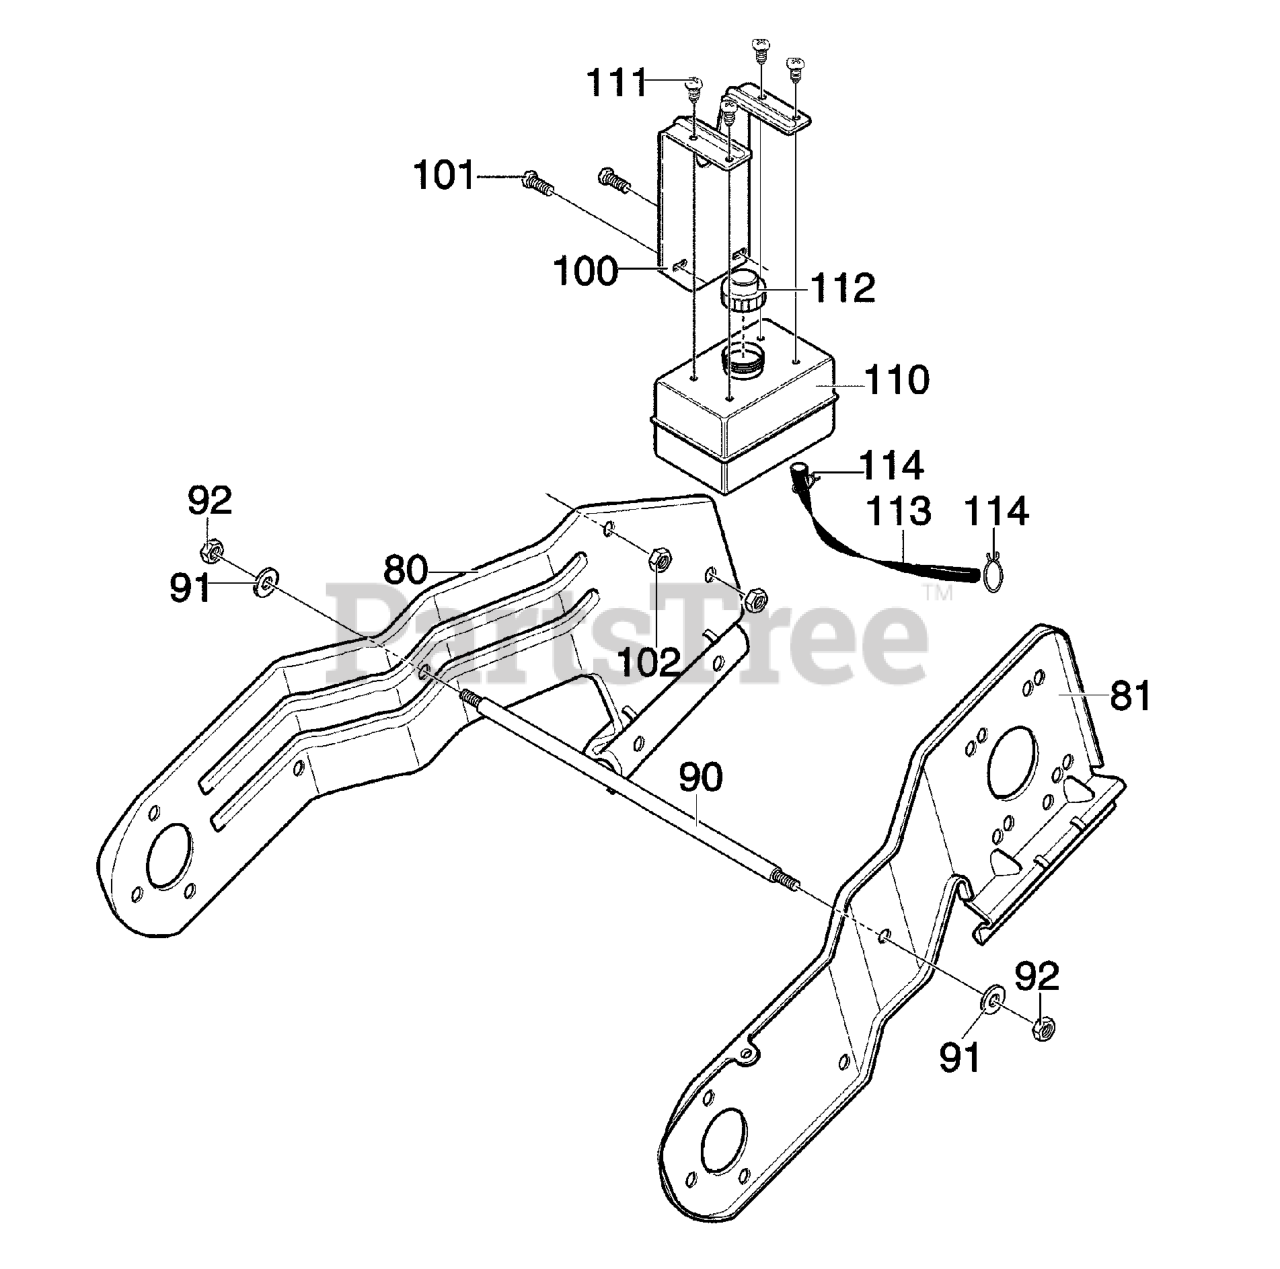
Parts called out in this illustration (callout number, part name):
80	FRAME SIDE SUPPORT RH
81	FRAME SIDE SUPPORT LH
90	ROD, SUPPORT
91	WASHER, HVSPTLK
92	NUT, 3/8-16 REGHEX
100	BRACKET, GAS TANK
101	SCREW, 1/4-20X.75
102	NUT, 1/4-20 REGHEXCTRLK
110	TANK, FUEL
111	SCREW, 1/4-14X.88 WAHHTAP
112	CAP, GAS-RED
113	TUBING 11.50 IN.
114	CLAMP, FUEL LINE
